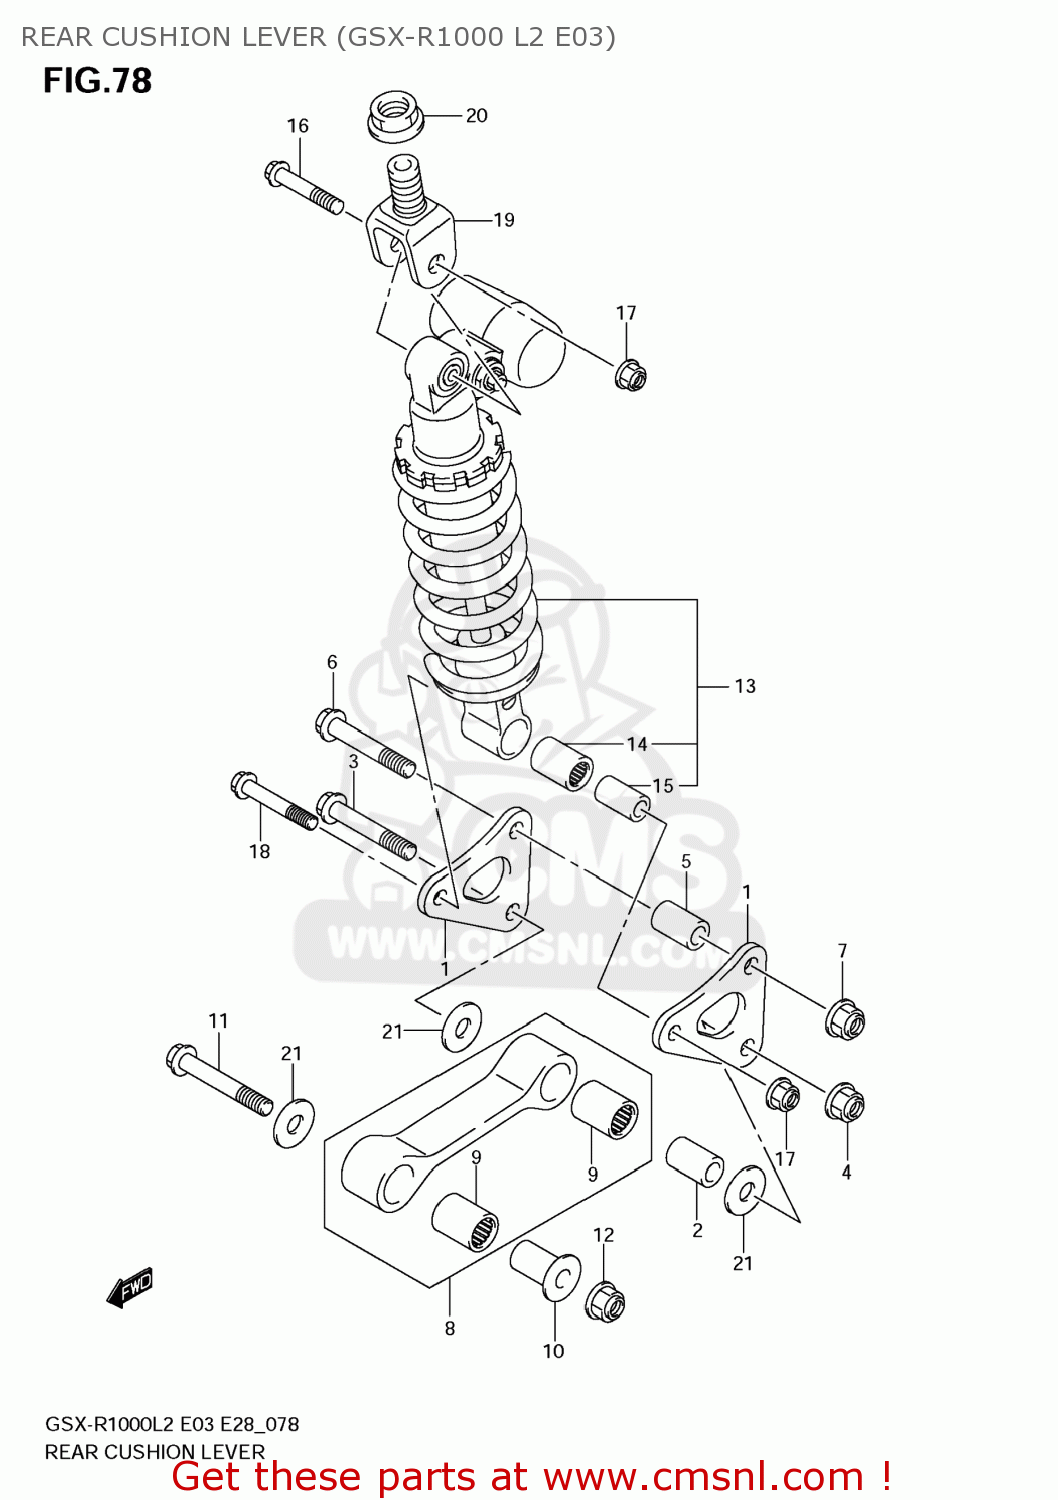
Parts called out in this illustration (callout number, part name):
1	LEVER,RR CUSHION
2	SPACER,RR CUSHION LEVER FR
3	BOLT,RR CUSHION LEVER
4	NUT
5	SPACER,RR CUSHION LEVER FR
6	BOLT,RR CUSHION LEVER
7	NUT
8	ROD SET,RR CUSHION LEVER
9	BEARING(20X27X32)
10	SPACER,RR CUSHION ROD FR
11	BOLT,RR CUSHION ROD
12	NUT
13	ABSORBER ASSY,RR SHOCK
14	BEARING(17X24X32)
15	SPACER,RR SHOCK ABS LWR
16	BOLT(10X55)
17	NUT
18	BOLT,RR SHOCK ABSORBER LWR
19	BRACKET,RR SHOCK ABSORBER UPR
20	NUT,RR SHOCK ABS BRACKET
21	WASHER(12X34X1)
